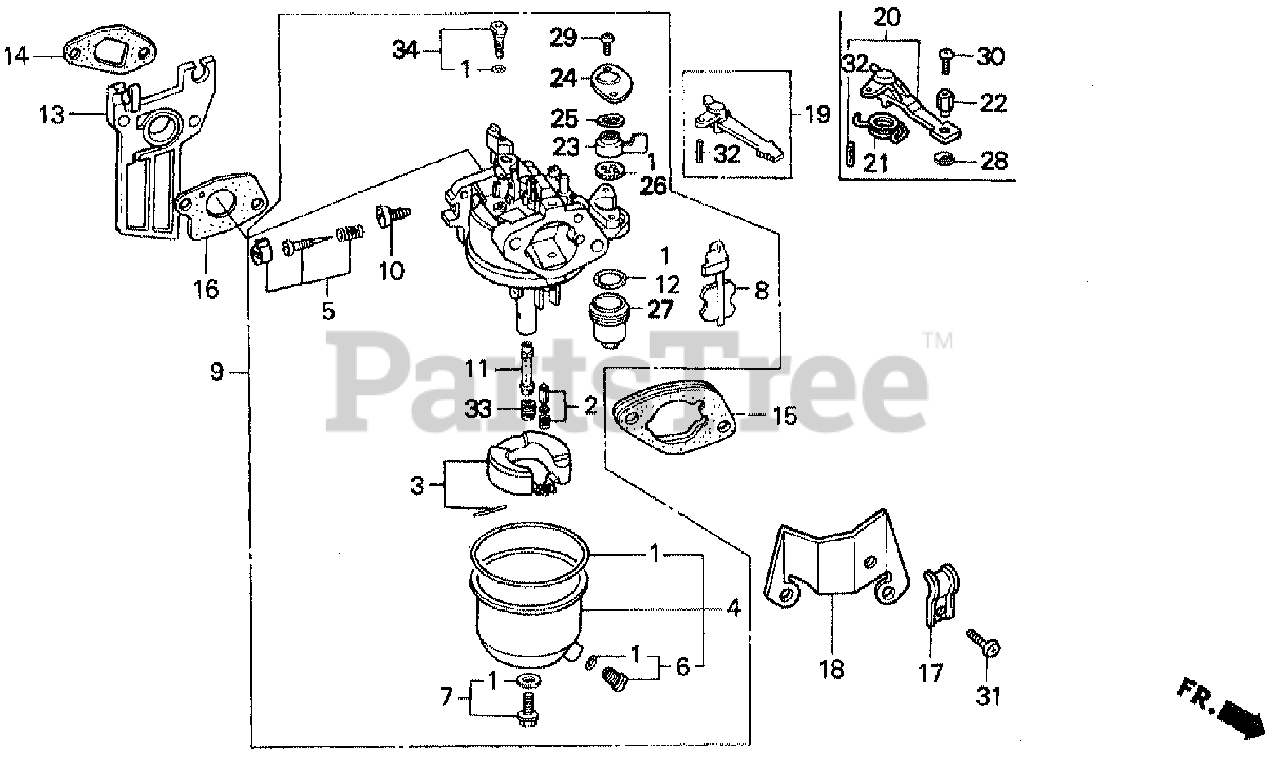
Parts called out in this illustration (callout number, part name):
1	GASKET SET
2	VALVE SET, FLOAT
3	FLOAT SET
4	CHAMBER SET, FLOAT
5	SCREW SET
6	SCREW SET, DRAIN
7	SCREW SET B
8	CHOKE SET
9	CARBURETOR ASSY. (BE65B B)
10	SCREW, THROTTLE STOP
11	NOZZLE, MAIN
12	GASKET, FUEL STRAINER CUP
13	INSULATOR, CARBURETOR
14	GASKET, INSULATOR
15	SPACER, CARBURETOR
16	GASKET, CARBURETOR
19	LEVER, CHOKE (STD)
23	LEVER, VALVE
24	PLATE, LEVER SETTING
25	SPRING, VALVE LEVER
26	GASKET, VALVE
27	CUP, FUEL STRAINER
29	SCREW, PAN (3X6)
29	SCREW, PAN (3X8)
32	PIN, SPRING (2X12)
33	JET, MAIN (#65)
33	JET, MAIN (#68)
33	JET, MAIN (#70)
34	JET SET, PILOT (#35)
